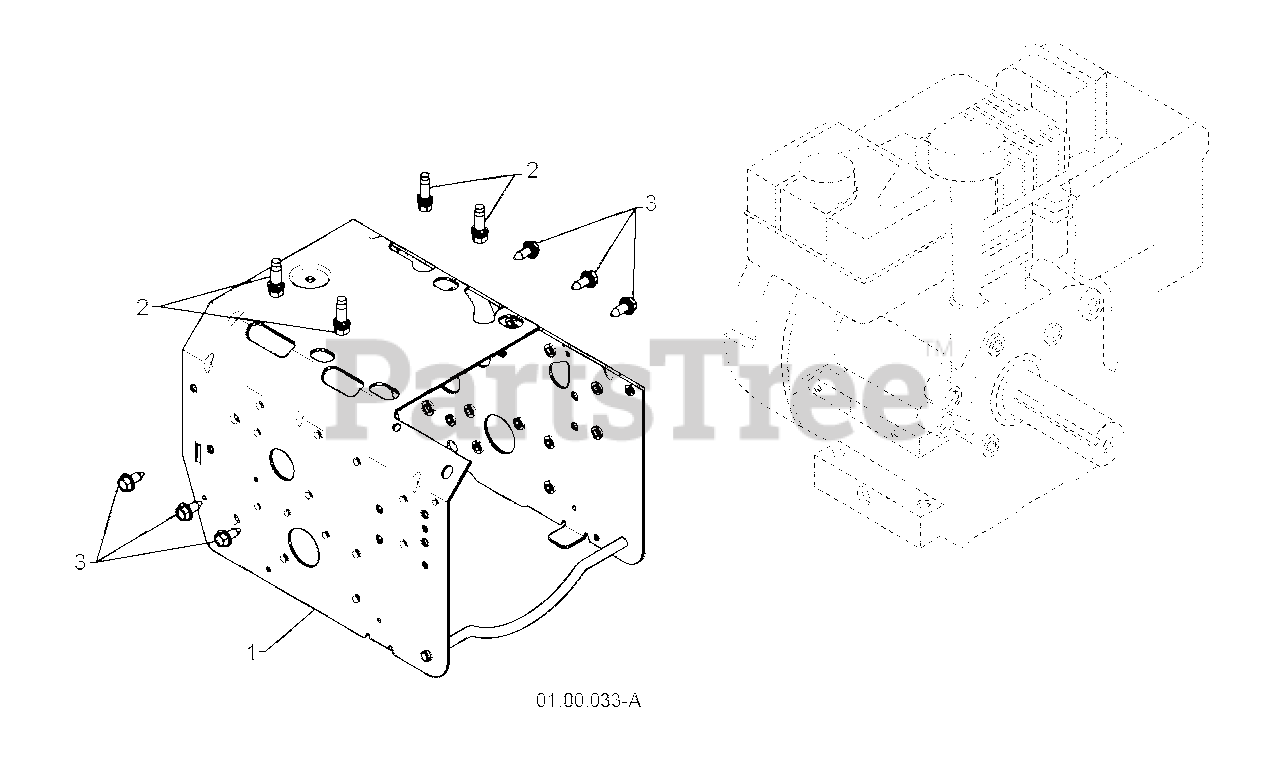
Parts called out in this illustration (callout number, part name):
1	FRAME.WELD.PNT.CHAIN.ORANGE
2	BOLT 3/8-16X1-1/8
3	BOLT.HEX.HD.WASHER.5/16-18X.75
